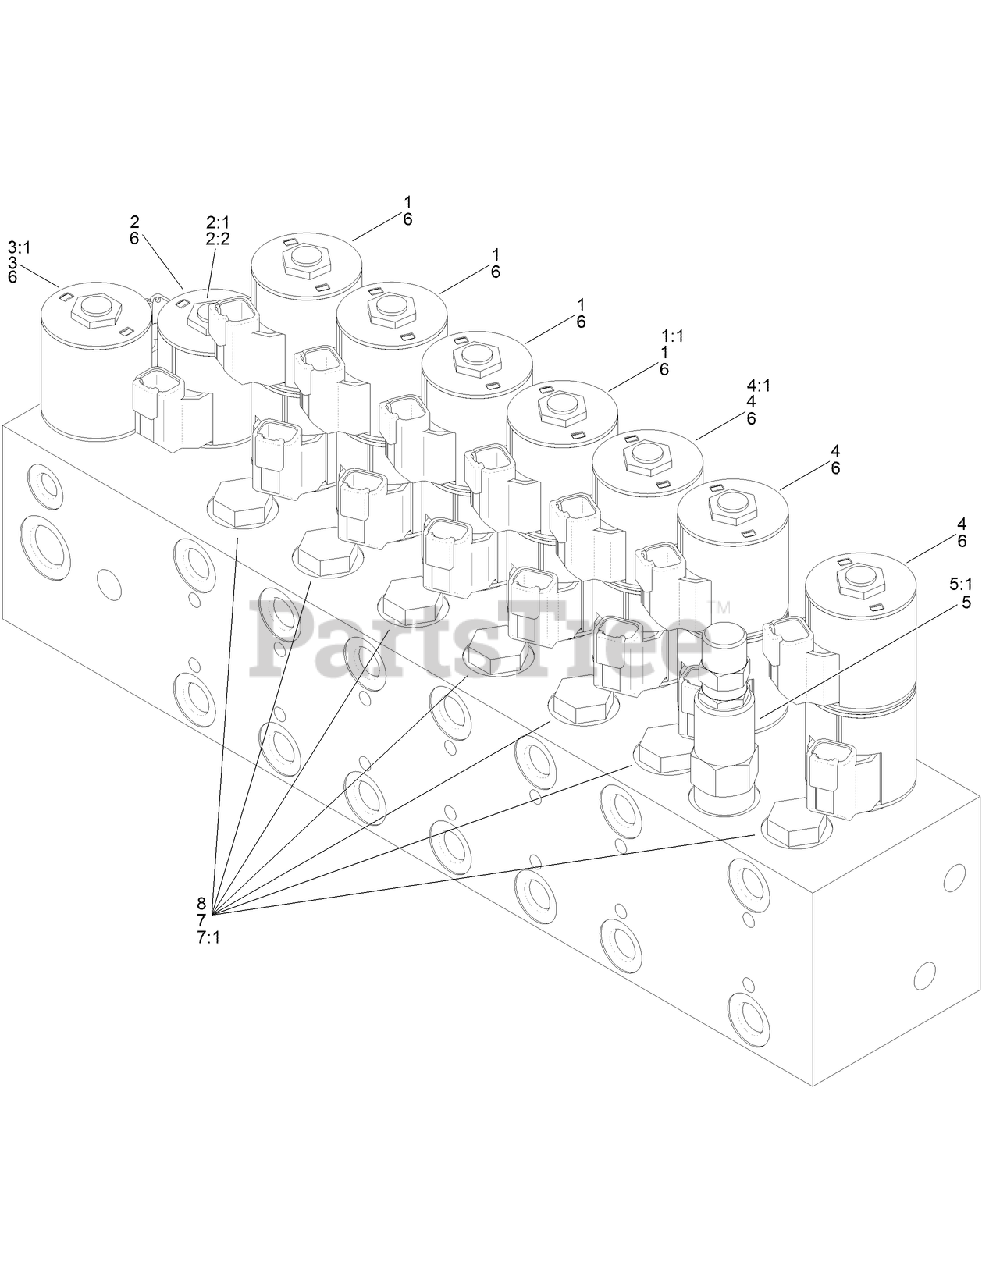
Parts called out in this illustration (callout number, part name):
1	VALVE-CARTRIDGE, MOTOR SPOOL
1:1	SPOOL VALVE SEAL KIT
2	SOLENOID VALVE ASM
2:1	SEAL KIT
2:2	NUT-COIL
3	VALVE-SOLENOID
3:1	SEAL KIT
4	SOLENOID ASM
4:1	SPOOL VALVE SEAL KIT
5	VALVE-REDUCING, PRESSURE
5:1	SEAL KIT
6	COIL-SOLENOID
7	CHECK VALVE ASM
7:1	SEAL KIT
8	PISTON-PILOT
